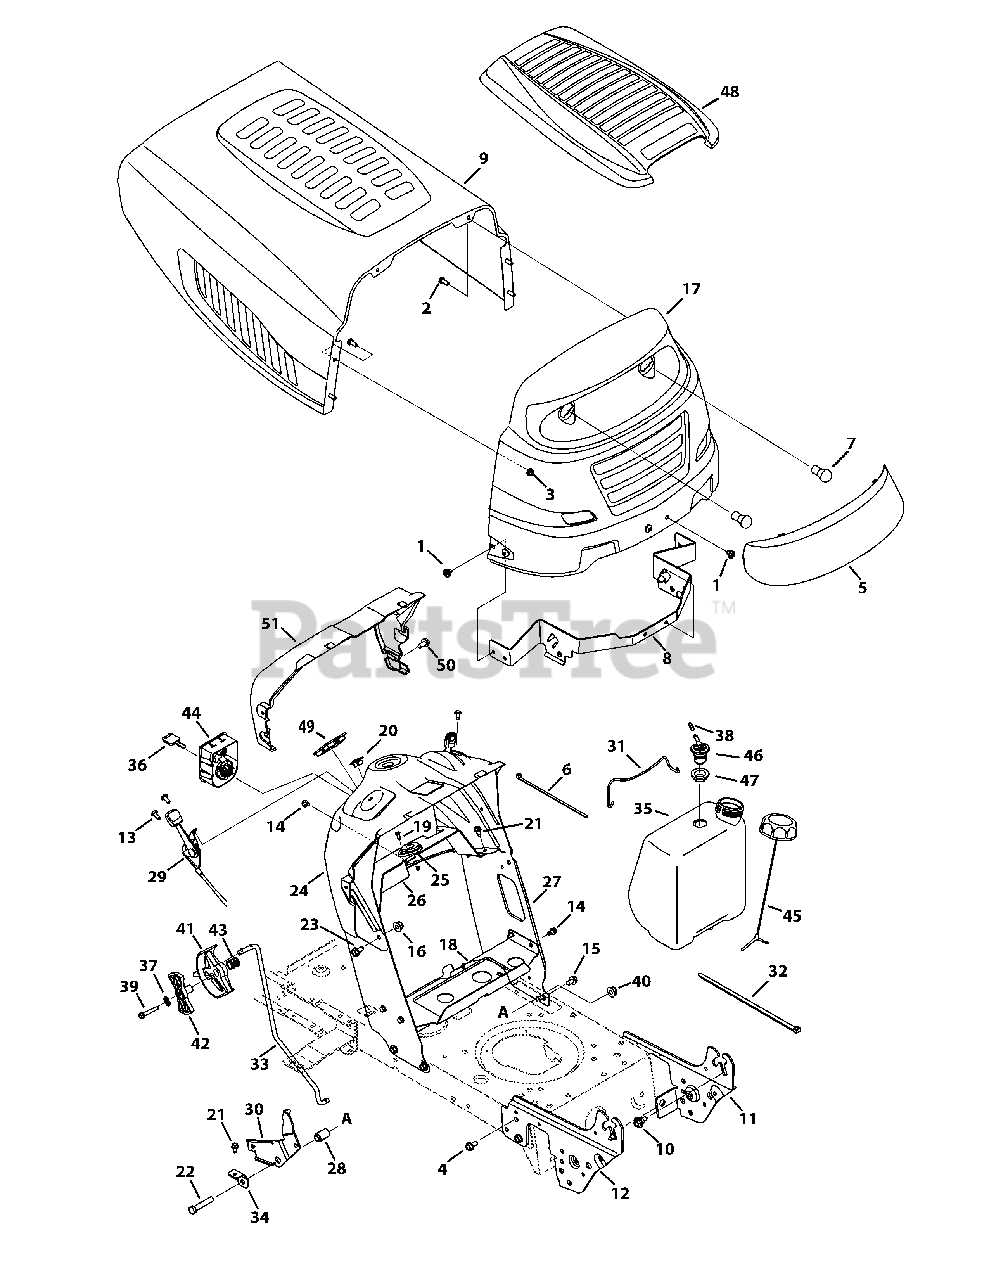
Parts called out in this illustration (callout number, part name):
1	Screw, 5/16-18 x .375
2	Hex Screw, 1/4-20 x .620
3	Flangelock Nut, 1/4-20
4	Screw, 5/16-18 x .750
5	Grill Lens
6	Cable Tie
8	Hood Pivot Bracket
10	Shoulder Screw, 5/16-18 x .43 x .29
11	Left Support Pivot Bracket
12	Right Support Pivot Bracket
13	Screw, 1/4-20 x .500
14	Screw, 1/4-20 x .500
15	Screw, 5/16-18 x .625
16	Flangelock Nut, 5/16-18
17	Grill
18	Gas Tank Support Bracket
19	Screw, #10-16 x .500
20	Choke Plug
21	Tap Screw, 1/4-20, 0.625
22	Hex Screw, 3/8-16 x 2.0
23	Hex Screw, 5/16-18 x .625
24	Dash, Upper
24	Dash, Upper RMC
25	Bearing, .628 ID x 1.36
26	Bracket, Steering Support
27	Dash, Lower
28	Flange Spacer, .390 x .671 x 1.095
29	Throttle/Choke Cable
30	Transmission Speed Latch, RMC
31	Battery Assembly Rod
32	Cable Tie
33	Speed Control Rod
34	Speed Latch Tab
35	1.36 Gallon Fuel Tank
37	Lock Washer, 1/4
38	Hose Vent, 3/16 EPA
39	Hex Washer Screw, 1/4-20 x 1.50
40	Flangelock Nut, 3/8-16
41	Shift Lever
42	Index Control
43	Compr. Spring, .72 OD x .78
44	Key Switch Module
45	Fuel Cap, 2.25"
46	Rollover Valve
47	Rubber Grommet, 23 x 3.55
48	Hood cover
49	Ammeter Plug
50	Screw, 1/4-15 x .750
51	Dash Collar
